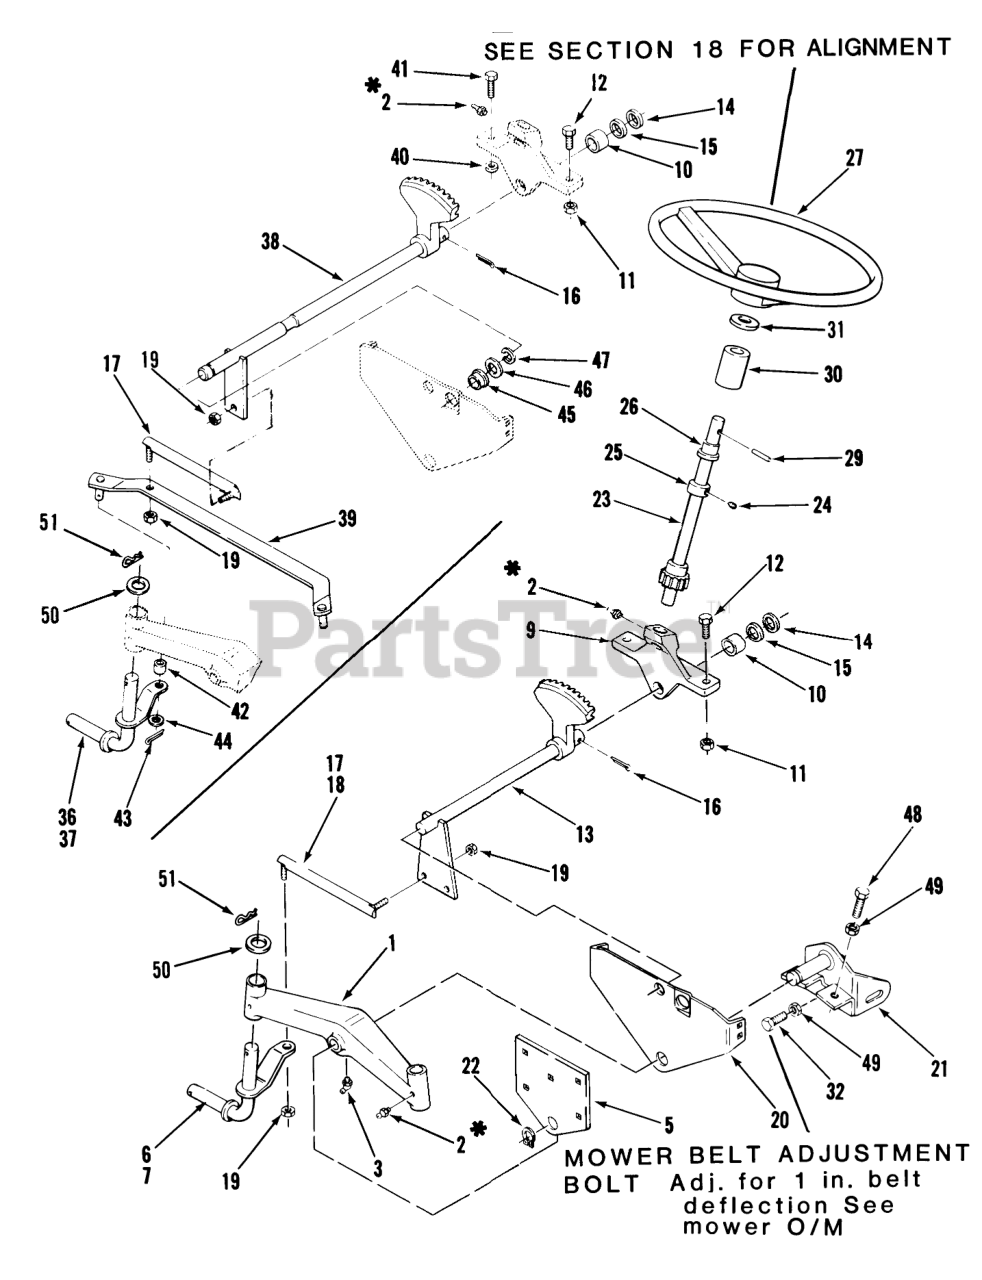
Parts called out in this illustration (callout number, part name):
1	AXLE-FRONT R
2	Zerk
3	FITTING-GREASE
5	PLATE-FRONT AXLE R
6	Front Spindle RH B-115 Only
7	Front Spindle LH B-115 Only
9	Support
10	BEARING-BRONZE
11	Nut
12	BOLT
13	ASSY-STRG SHFT LO R
14	WASHER-SHIM
15	WASHER
16	PIN-4
17	25LL JOINT ASSY R R
18	BALL JOINT ASSY L R
19	NUT-6
20	Support Front Axle
21	ASSY-FRONT HANGER R
22	Snap Ring
23	ASSY-STEER SHFT U R
23	ASSY-STRG SHFT-UP R
24	SCREW-SET
25	Collar
26	BEARING-FLANGED
27	STEERING WH 13" PLAS
29	Pin-Roll
30	Collar 208-3 Only
30	TUBE-STEERING
31	WASHER-FLAT
32	SCREW-HH
36	Front Spindle RH B-165 Only
37	Front Spindle LH B-165 Only
38	Assy Strg Lower B-165 Only
39	ASSY-TIE ROD R
40	WASHER
41	BOLT
42	SPACER
44	WASHER
45	BUSHING
46	WASHER SPECIAL
47	Ring
48	Bolt
49	Nut
50	WASHER
51	COTTER PIN-4
